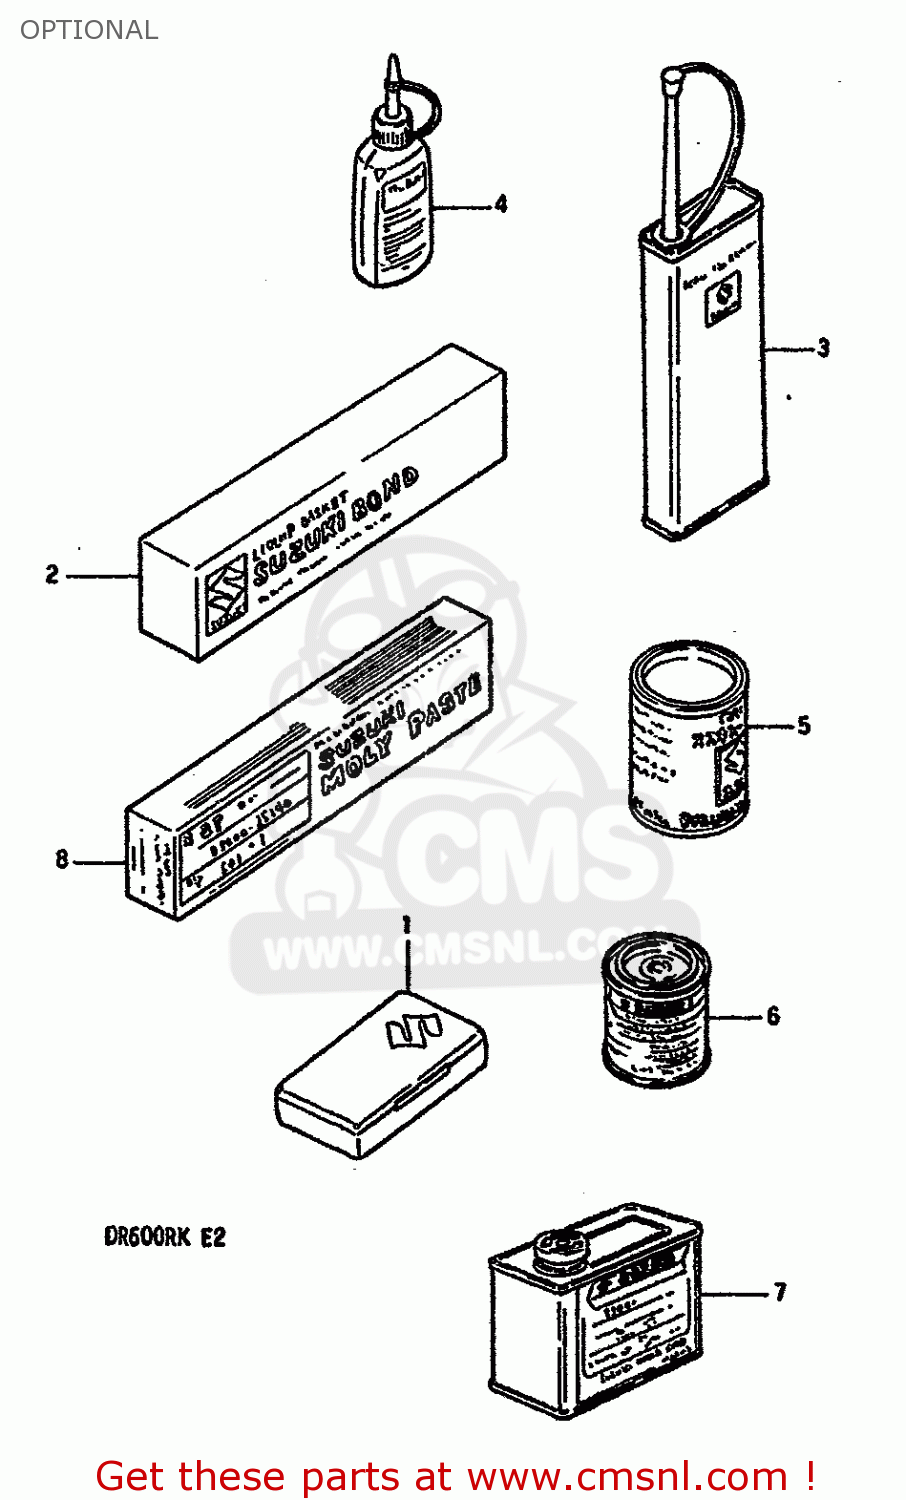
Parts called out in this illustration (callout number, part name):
1	TUBE REPARING TOOL
2	LIQUID GSKT NO.1207B 100G BLK
3	THREAD LOCK NO.1401 CLEAR 200G
4	THREAD LOCK NO.1342
5	GREASE(C)EP2 LITHIUM 150G
6	PAINT (SUPER WHITE)
7	PAINT (ROCKY WHITE)
8	SUZUKI MOLY PASTE
